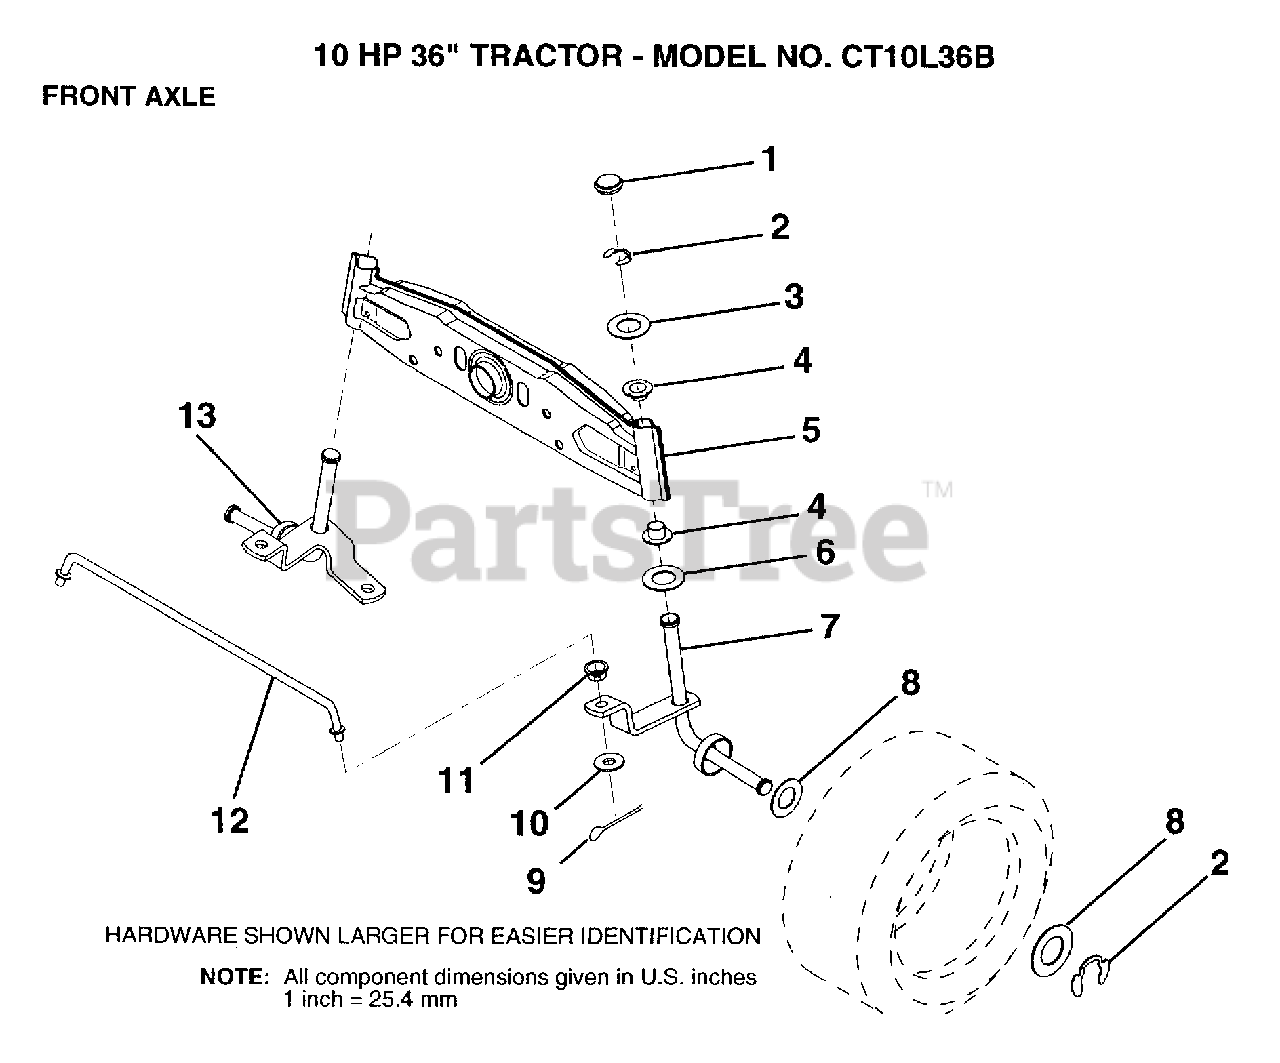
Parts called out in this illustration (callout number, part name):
1	CAP
2	RING
3	WASHER
4	NYLINER
5	AXLE FRONT
6	WASHER .T
7	SPINDLE RH
8	WASHER
9	COTTER PIN
10	WASHER
11	BUSHING.DRAGLINK
12	ROD TIE
13	SPINDLE LH
